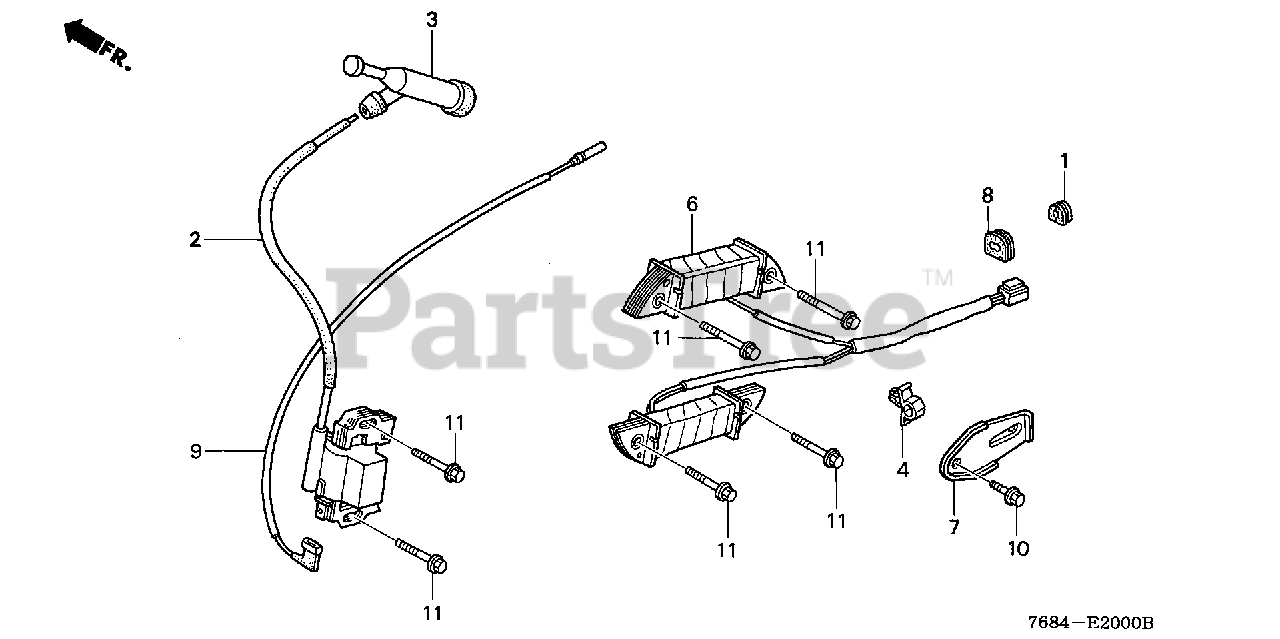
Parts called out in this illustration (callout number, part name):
1	GROMMET, OIL PIPE HOLDER
2	COIL ASSY., IGNITION
3	CAP ASSY., NOISE SUPPRESSOR (NICHIWA Y-EZ RTFM256)
6	COIL ASSY., LAMP (12V/50W)
7	CLAMP, WIRE
8	GROMMET, WIRE
9	WIRE, STOP SWITCH (370MM)
10	BOLT, FLANGE (6X12) (CT200)
11	BOLT, FLANGE (6X28) (CT200)
